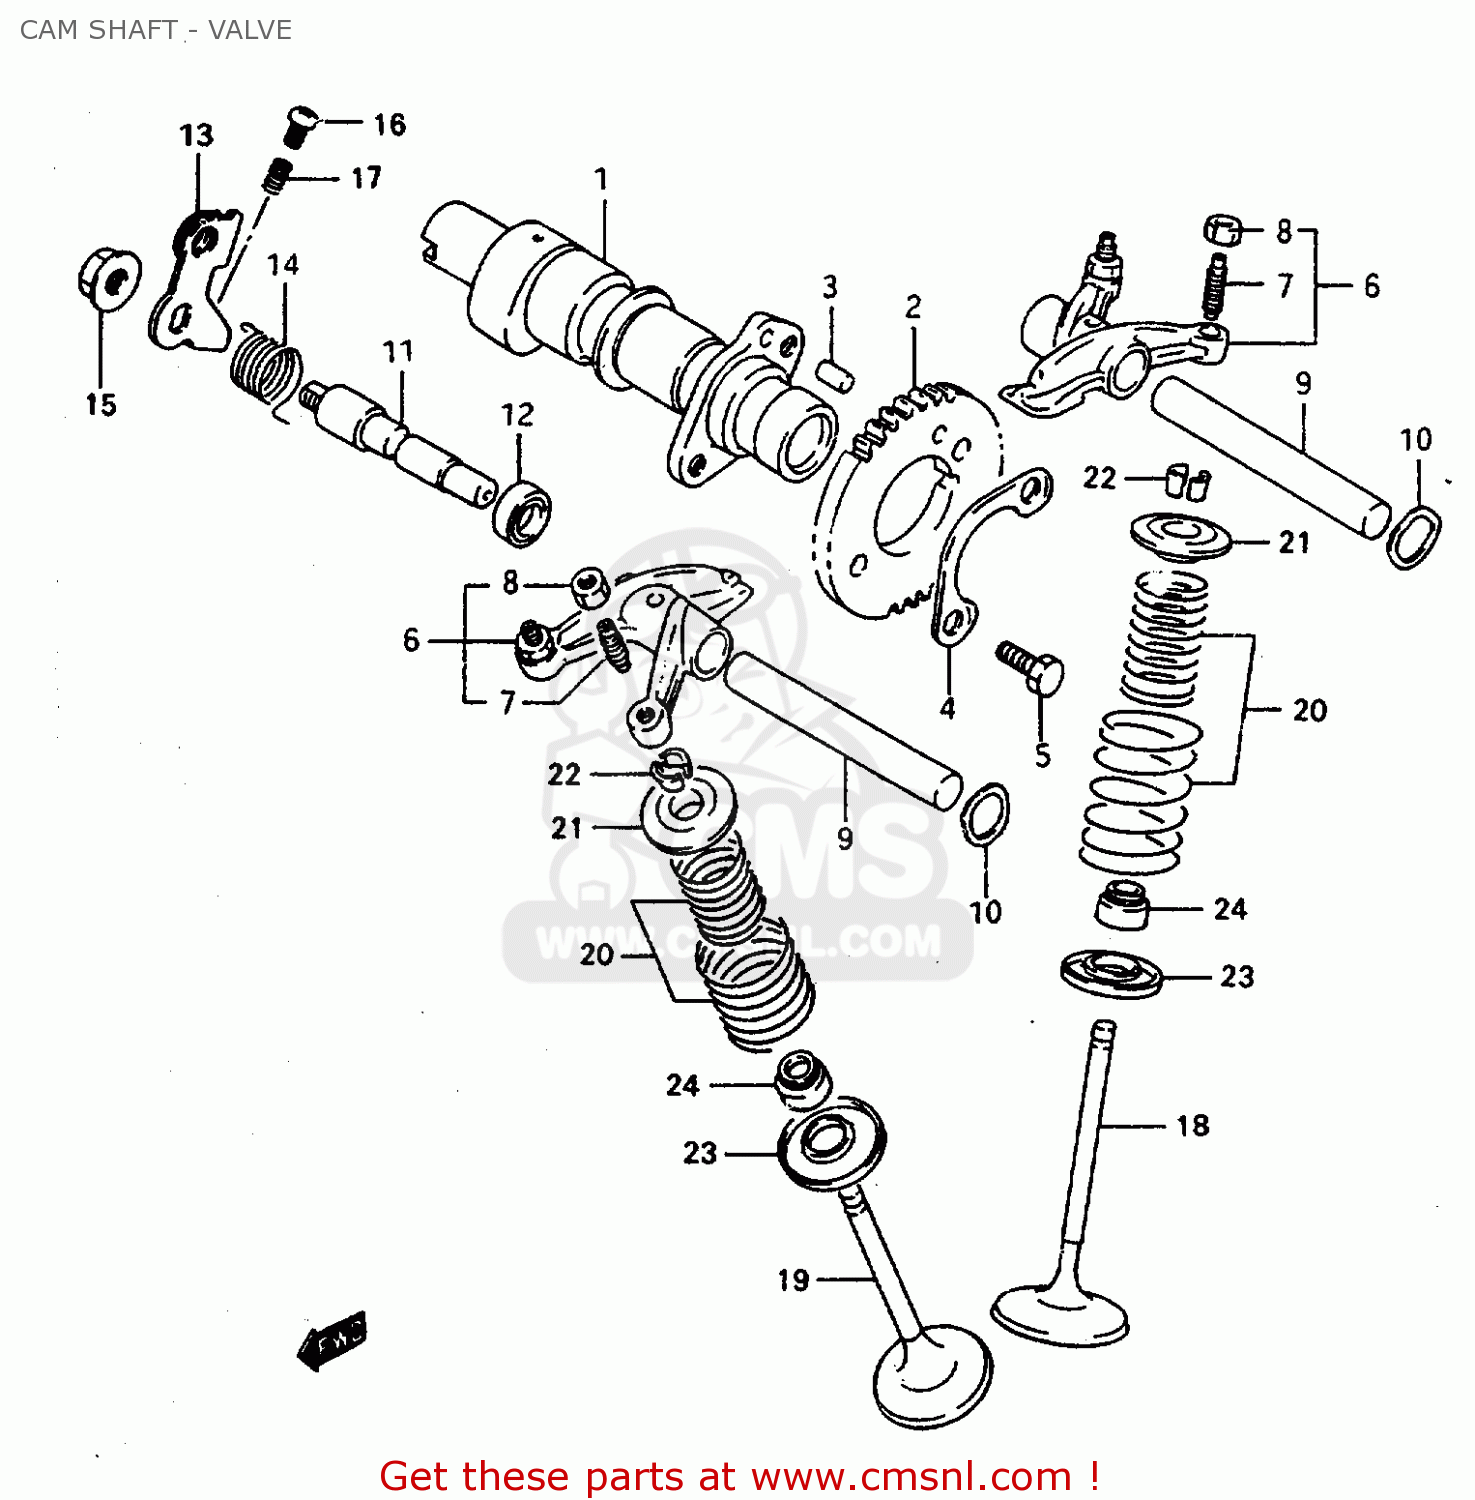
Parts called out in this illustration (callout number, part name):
1	CAMSHAFT
2	SPROCKET,CAMSHAFT
3	PIN
4	WASHER,SPROCKET
5	BOLT(6X14)
6	ARM,VALVE ROCKER
7	SCREW,TAPPET ADJUSTING
8	NUT,ADJUSTING SCREW
9	SHAFT,VALVE ROCKER ARM
10	WASHER
11	SHAFT,DECOMP.
12	SEAL,OIL(10X17X6)
13	LEVER, DECOMP SHAFT
14	SPRING
15	NUT
16	SCREW
17	SPRING
18	VALVE,INTAKE
19	VALVE,EXHAUST
20	SPRING SET,VALVE
21	RETAINER,VALVE SPRING
22	COTTER,VALVE
23	SEAT,VALVE SPRING
24	SEAL,OIL(7X14.4X9)
